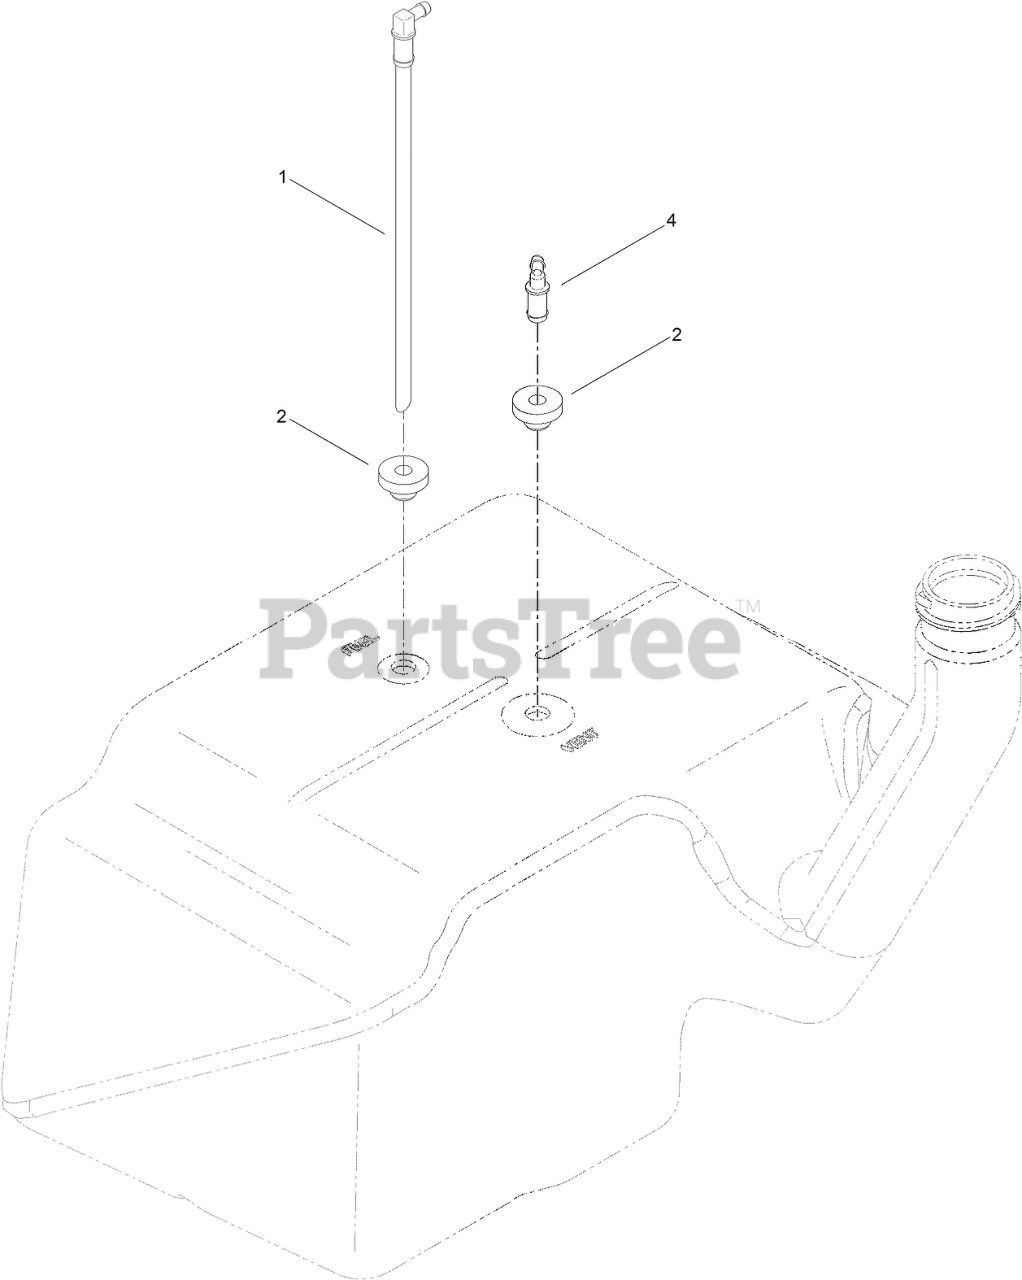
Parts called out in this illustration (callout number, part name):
1	CONNECTOR-ELBOW, 90 DEG
2	BUSHING
4	FITTING-PLASTIC
